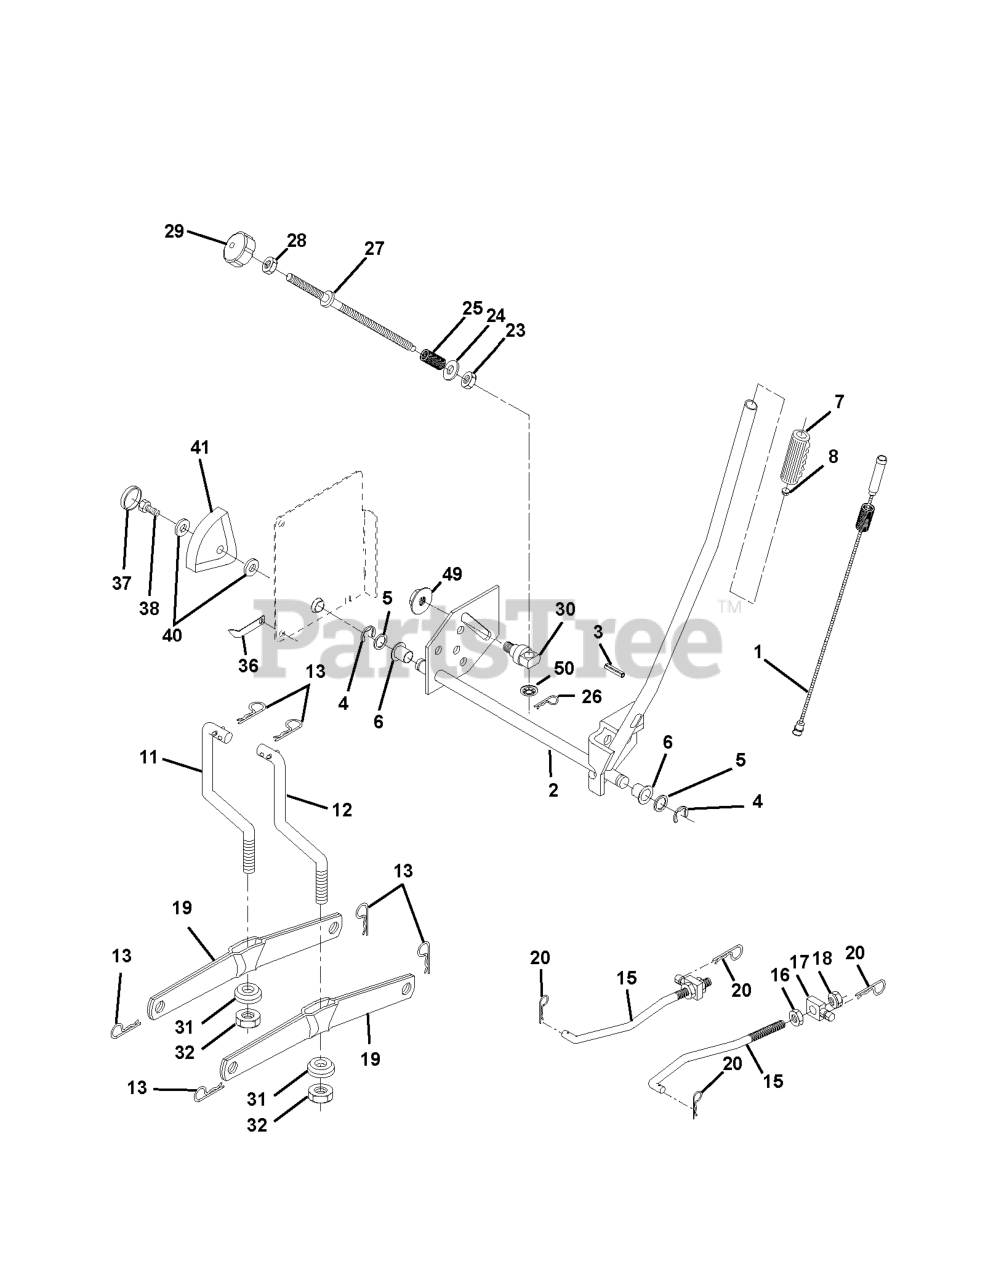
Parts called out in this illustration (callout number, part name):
1	WIRE ASM INNER W/ PLUNGER LT
2	SHAFT ASM R HANDLE
3	PIN GROOVE.
4	RETAINING RING LT
6	BEARING.NYLON
7	GRIP HANDLE
8	PLUNGER BUT KIT
11	LINK
12	LINK
13	RETAINER-SPRNG RB
15	LINK FRONT
16	NUT.HEX.JAM.1/2-13
17	TRUNION
18	NUT LTV
19	ARM.REAR.SUSPENSION
20	SPRING RETAINER
25	SPRING**
26	RETAINER CLIP
27	ROD ADJ LIFT
28	NUT
29	KNOB INF 3/8-16
31	BEARING PIVOT
32	NUT CROWNLOCK 3/8-24
36	POINTER, HEIGHT INDICATOR(2 2)
38	SCREW 5/16-18X1
41	HEIGHT INDICATOR
49	NUT
50	NUT PUSH M
